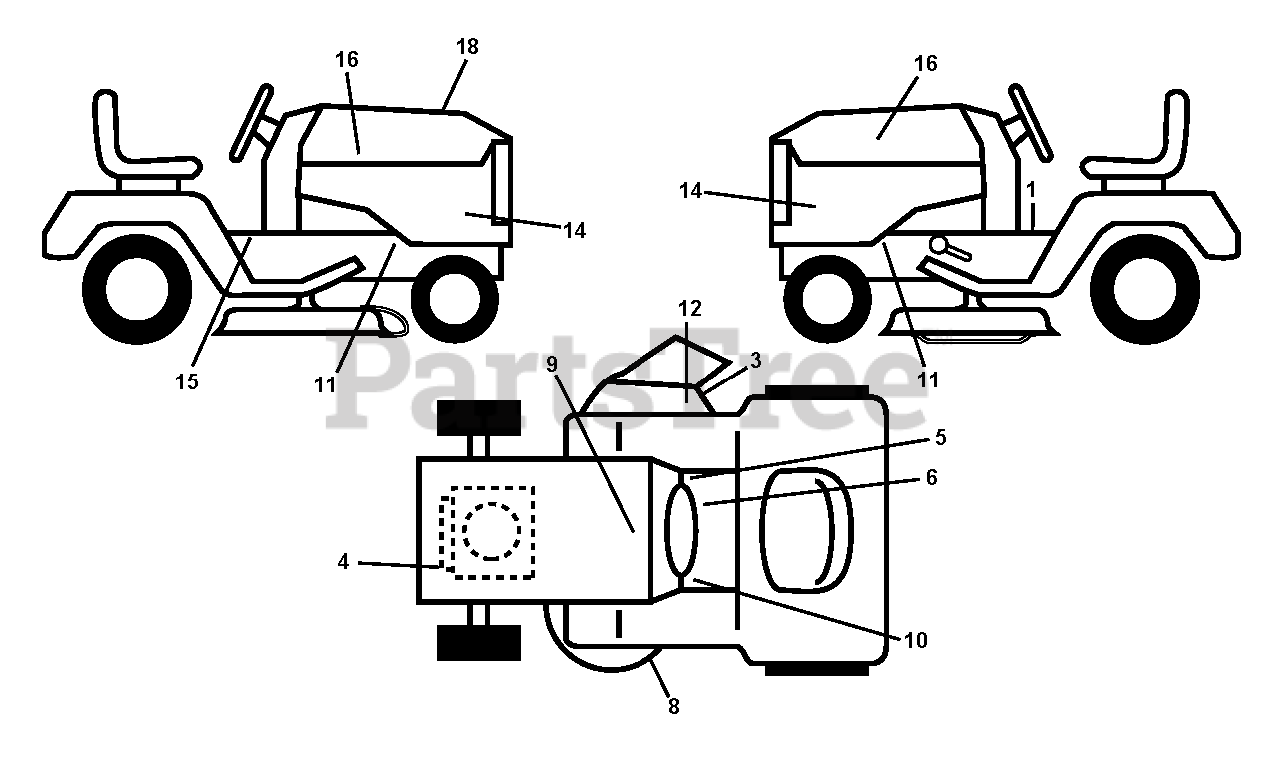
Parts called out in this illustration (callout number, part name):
1	LABEL
3	DECAL, DEFLECT WARNING
4	DECAL
5	DECAL PARK BRAKE
6	DECAL
8	DECAL.MOWER.SCH.48/54
9	DECAL BTRY SYMBOLS
10	DECAL
12	DECAL.INTERNATIONL.CUTFINGER
14	DECAL PNL SD.
15	DECAL.FENDER
16	RP.DECAL.BADGE.170MM.TEXTLOGO
18	DECAL RPL KO
